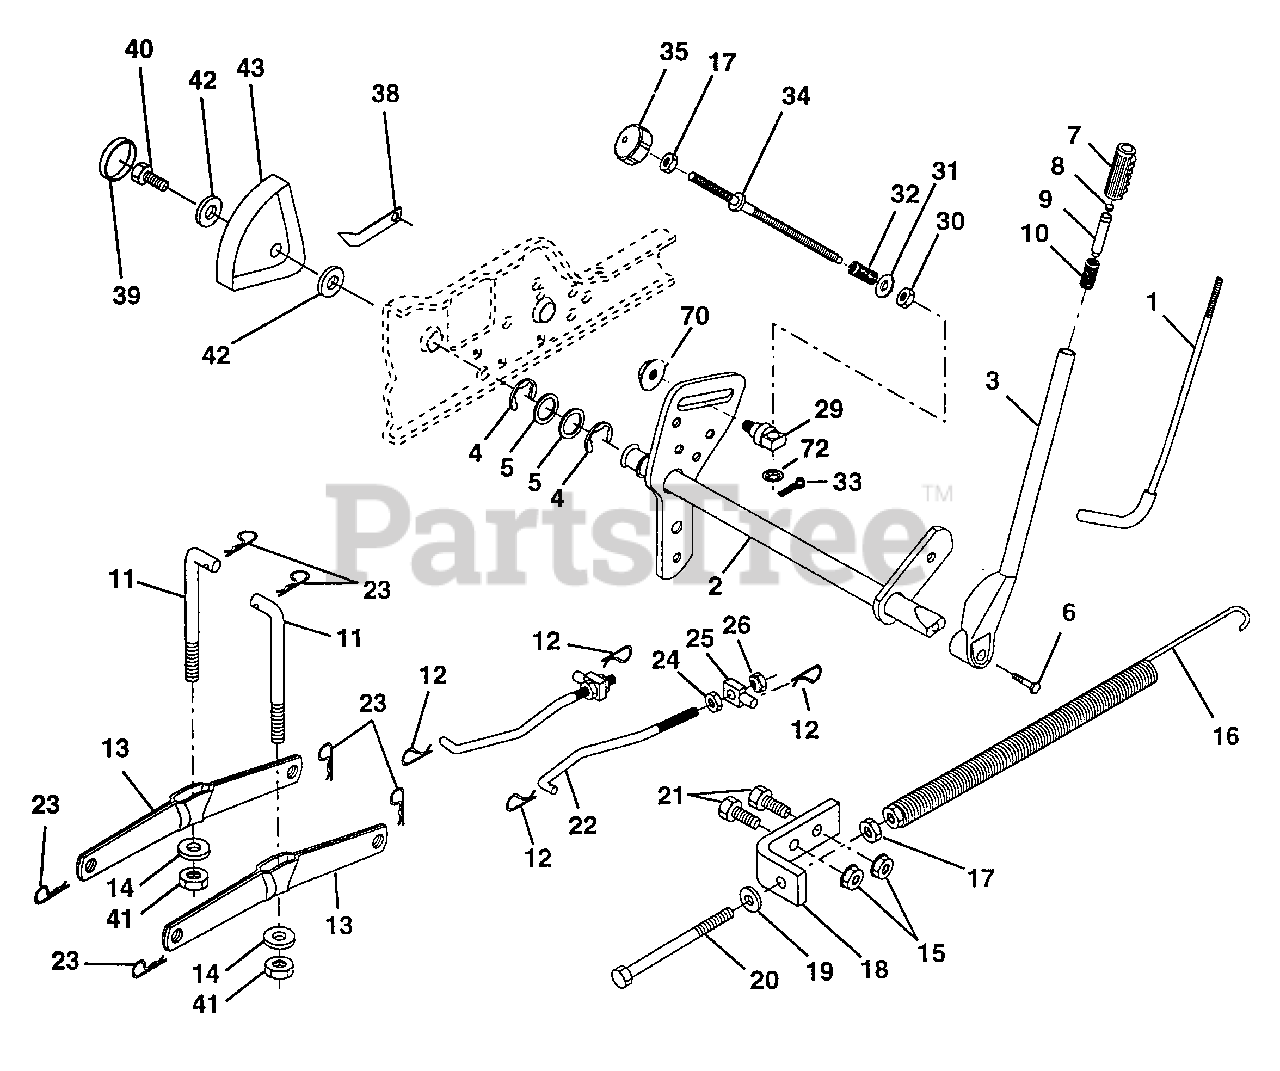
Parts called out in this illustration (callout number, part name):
1	Rod Asm., Lever
2	Shaft Asm., Lift Vgt (AYP part number)
3	Lever Asm., Lift Rh
4	E-Ring Truarc #5133-87
5	Washer 29/32 x 1-1/4 x 16 Ga.
6	Bolt, Fin Hex 3/8-16 x 1-1/2
7	Grip, Handle Bicycle
8	Button, Plunger (AYP part number)
9	Plunger, Lever Lift (AYP part number)
10	Spring 2-1/8"
11	Link Lift (AYP part number)
12	Retainer, Spring
13	Arm, Suspension Vgt
14	Bearing (AYP part number)
15	Nut, Crownlock 3/8-16
16	Spring Asm., Assist Lift
17	Nut, Hex Jam 3/8-16 Unc
18	Bracket, Spring Assist
19	Washer 13/32 x 13/16 x 16 Ga.
20	Bolt, Adjust Spring Assist
21	Bolt, Fin Hex 3/8-16 x 1
22	Link, Front
23	Retainer, Spring (AYP part number)
24	Nut, Jam Hex 1/2-13 Unc
25	Trunnion (AYP part number)
26	Nut, Lock W/Wsh 1/2-13 Unc (AYP part number)
29	Trunnion Infin Height
30	Nut, Special
31	Washer 13/32 x 5/8 x 16 Ga.
32	Spring, Compression Inf Hgt
33	Pin, Cotter 3/32 x 1/2 (AYP part number)
34	Rod, Adj Lift
35	Knob, Inf 3/8-16 Unc
38	Pointer Height Indicator
39	Plug, Hole Blk. 1.485/1.515 Dia.
40	Screw Thdrol 5/16-18 x 3/4
41	Nut, Crownlock 3/8-24 (AYP part number)
42	Washer 11/32 x 1-1/2 x 10 Ga.
43	Scale, Indicator Height
70	Nut Hex Flange Lock
72	Nut Push Phos & Oil
